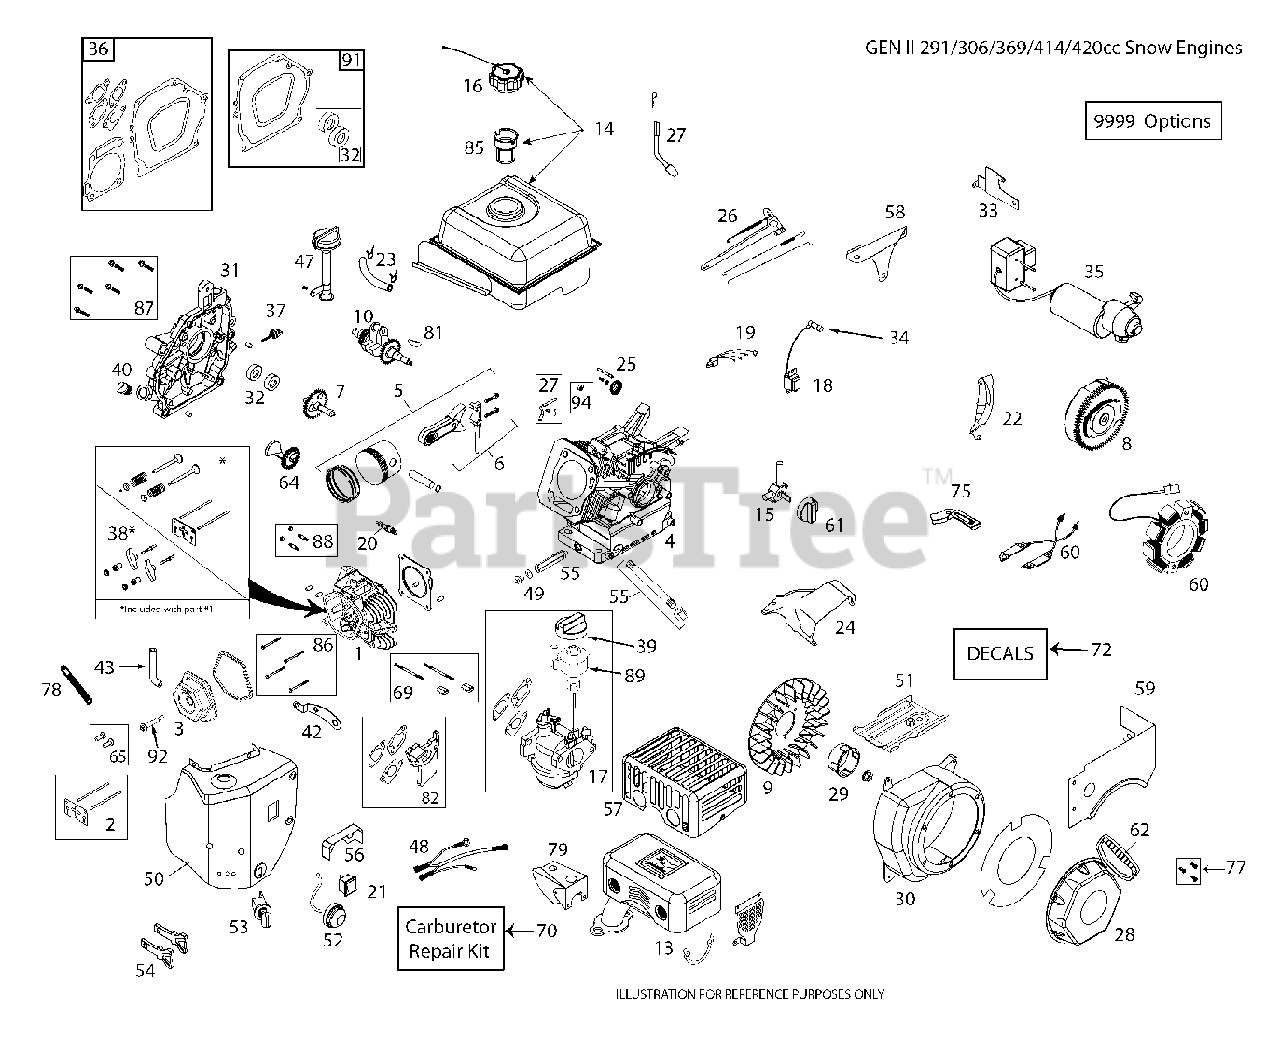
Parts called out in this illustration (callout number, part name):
1	CYLINDER HEAD LCT 178 INCLUDES
2	PUSH ROD TAPPET KIT
3	VALVE.COVER.LCT.414CC.
4	CYLINDER LCT 369 SKSN3333.1
5	PISTON.AND.ROD.ASSY(SK4141400)
6	CONNECTING ROD ASSEMBLY
7	CAMSHAFT(SK4141600)
8	FLYWHEEL.EL.ST.SKSN4408.1
9	FLYWHEEL.FAN(SK4144000)
10	CRANKSHAFT KEYED #18 LCT 414C
13	MUFFLER ASSY LCT SNO
14	FUEL.TANK.ASSY.SNOW(SKSN4300)
15	FUEL.PETCOCK.SNOW(SKSN4900)
16	FUEL.TANK.CAP.SNOW(SKSN4301)
17	CARBURETTOR L18D LCT 369
18	IGNITION.COIL.(CDI).291-414CC
20	SPARK.PLUG(SK2911550)
21	ON/OFF.SWITCH.SNOW(SKSN4403)
22	SHIELD.U/FYWHL.CHARG(SKSN4604)
23	FUEL HOSE KIT
24	RP TOP SHIELD
25	GOVERNOR.GEAR.ASSY(SK4142900)
26	GOVERNOR.ARM.ASSY(SKSN4502)
27	GOVERNOR.SHAFT(SK4143100)
28	RECOIL.START.ASSY.SNW(SKSN4600
29	STARTER.CUP.SML.SNOW(SKSN4601)
30	BLOWER HOUSING.LCT 369 GLOSS
31	CRANKCASE.COVER.LCT.414CC.HIGH
32	OIL SEAL KIT NON-GENERATOR
33	ELECTRIC.START.BRKT(SKSN4405)
34	SPARK.PLUG.BOOT.SNW,SKSN4691.1
35	ELEC.START.ASSY.SNOW(SKSN4400)
36	GASKET KIT ENGINE LCT 369
37	DIPSTK.OIL.BLK.LCTSK4143711.1
38	ROCKER ARM KIT
39	CHOKE.KNOW.SNOW(SKSN4500)
40	NONREMVABLE.OIL.PLUG(SK4143715
42	CDI.BOX.BRKT.SNOW(SKSN4402)
43	BREATHER TUBE LCT 291/369/414
47	HIGHOIL.FILL.ASSY.KIT(SKSN4911
48	WIRE.HARNESS(SKSN4406)
49	OIL.DRAIN.PLUG
50	BOX HEATER ASM 414 LCT
51	SHIELD.CYLINDER.SNOW(SK4141010
52	PRIMER.BULB.ASSY(SKSN4304)
53	KEY.SWITCH.ASSY.SNOW(SKSN4401)
54	KEY SET(2 KEYS) SKSN0407.1
55	OIL PIPE DRAIN EXTENDED.LCT SK
56	SHIELD.VAPOR(SKSN4606)
57	MUFFLER (SKSN2210.1)
58	PLATE.GOVERN.LINK.S
59	SKIRT FUEL TANK
60	ALTERN.60WATT.SKSN2402.1
61	FUEL KNOB-SNOW
62	HANDLE.RECOIL.DELUXE.LCT
64	COUNTER WEIGHT KIT
65	TAPPET KIT.LCT.SK2911005.1
69	STUD.CARB.MOUTING.KIT.414CC
70	CARBURETTOR REPAIR KIT 291CC/4
77	BOLT.KIT.RECOIL.LCT.ALL.ENGINE
78	STRAP.RETAINING.TUBE.BREATHER.
79	SHIELD CARBURRETOR COVER 414
81	KEYS.FLYWHEEL.208/414CC.5PACK
82	SPACER.CARBURETOR.414CC.LCT
85	STRAINER.FUEL.TANK.LCT.208CC
86	KIT.BOLT.CYLINDER.HEAD.(4PC)
87	KIT.BOLT.CRANKCASE.COVER.414CC
88	STUD.MUFFLER.KIT.LCT
89	KNOB LCT.SKSN5325.1 SPEED
91	GASKET KIT CRANKSHAFT.LCT
92	CENTER VALVE COVER BOLT
94	SEAL GOVERNOR SHAFT OIL.LCT
9999	HIGH ALTITUDE JET 6000FT
